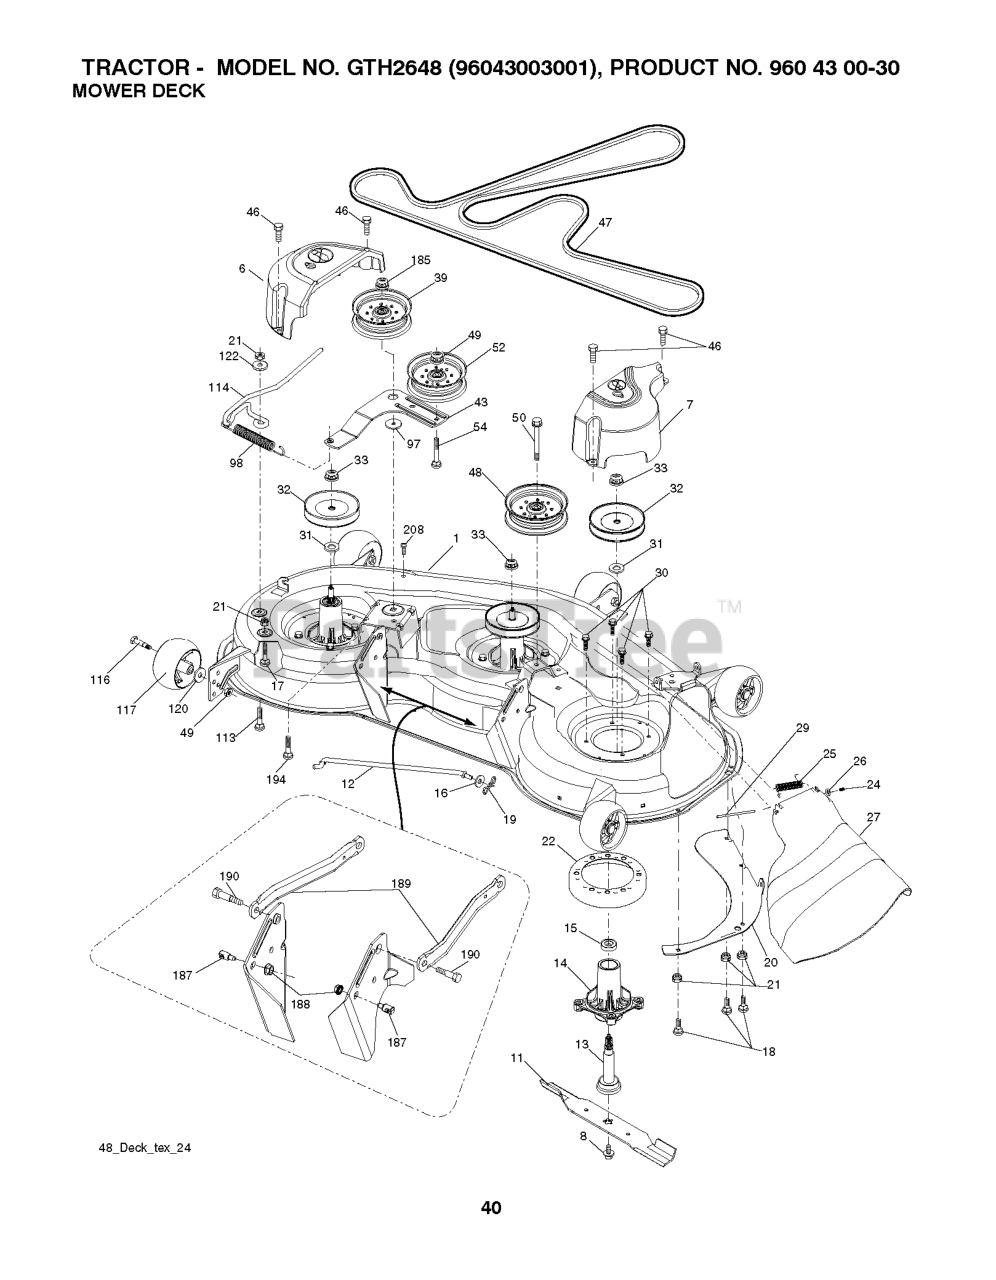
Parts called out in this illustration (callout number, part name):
1	DECK.PNT.WELDMENT.48"T
6	COVER.MANDREL.LH.48"(2 2)
7	COVER.MANDREL.RH.48"
8	BOLT 7/16 ASM BLADE
11	48" HI-LIFT BLADE
12	ROD.ANTI.SWAY.48/54"TE
13	SHAFT ASM MANDREL
14	RP.HOUSING.MANDREL.4PT.
16	WASHER
17	BOLT.CARR.5/16-18X5/8.SHORT
18	BOLT
19	PIN.COTTER.5/16.BOW TI
20	BAFFLE, VORTEX MWR
21	LOCKNUT
22	STRIPPER.MANDREL.ROUND.BLACK
24	CAP-SLEEVE LT
25	SPRING, TORSION
26	NUT PUSH M
27	DEFLECTOR SUBS TO 532 180655
29	ROD.HINGE
30	SCREW, WASHER HEAD
31	WASHER.SPACER.MANDREL
32	PULLEY MANDREL
33	NUT.FLANGE.LOCK.TOP
39	RB PULLEY.IDLER.4.50/HUB SPEC
46	SCREW.1/4-20X5/8
47	BELT.DRIVE.DECK
48	PULLEY.IDLER.48"PRIMARY
49	NUT LOCK FLG 3/8-16 UNC
50	BOLT.3/8-16X1.50
52	PULLEY.IDLER.2006
54	SCREW TT 3/8-16X2-1/4 UNC
98	SPRING, DECK DRIVE
114	ROD.TENSION.RELIEF.TEX (2 2)
116	BOLT.SHOULDER.3/8-16X3-5/8.
117	RP WHEEL. GUAGE RALLY
120	WASHER
122	BUSHING.RELIEF.TENSION
185	NUT.LOCK.FLANGE.7/16
187	STUD.FASTNER.W/ANTI-ROTATE
188	NUT LOCK HEX FLANGE 5/16-18
189	ARM.SUSPENSION.MOWER
190	BOLT.SHOULDER
194	BOLT.CARR.SQNK.7/16
208	SCREW 3/8-16X1/2
